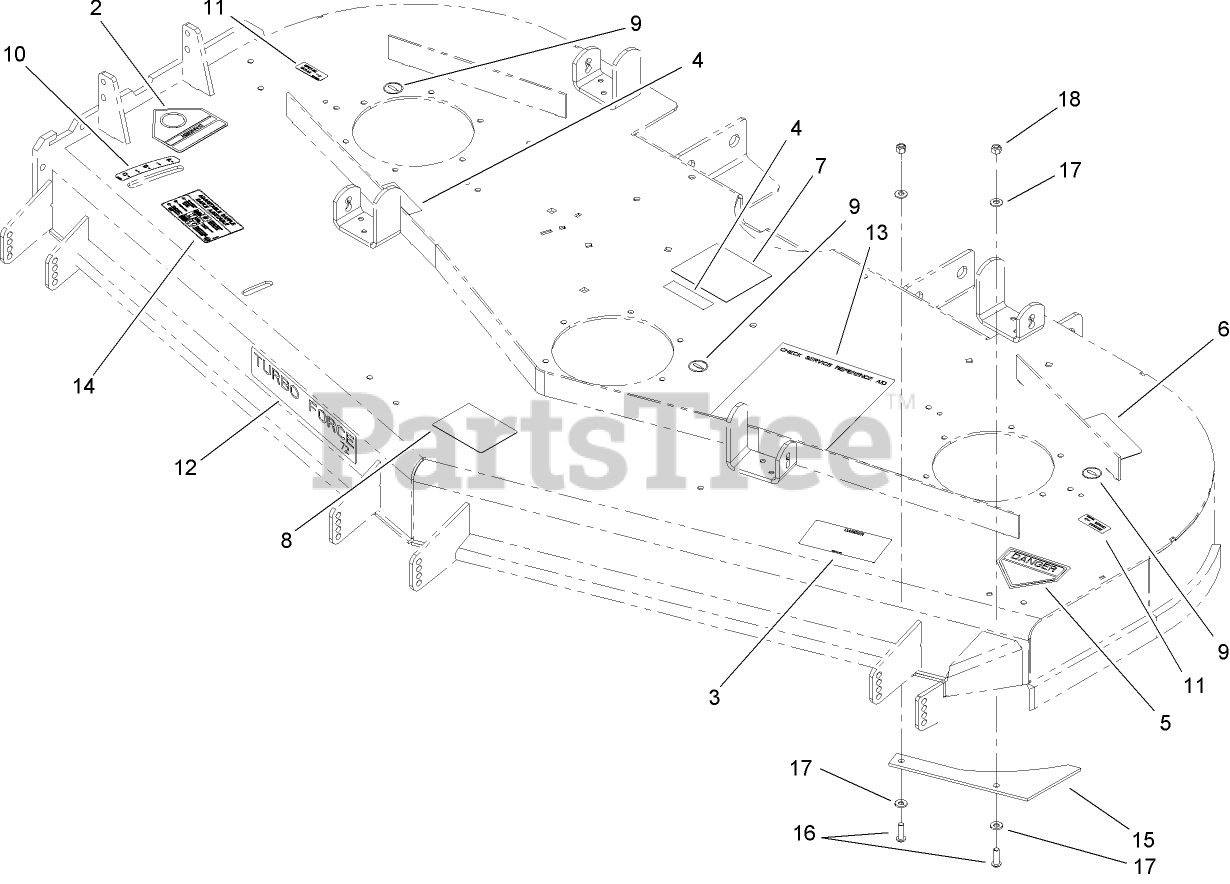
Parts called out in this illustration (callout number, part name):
2	DECAL-DANGER
3	DECAL-DANGER, THROWN OBJECT
4	DECAL-COVER, MISSING
5	DECAL-DANGER
6	DECAL-TORQUE
7	Decal-Routing, Belt
8	DECAL-SCALP, ANTI
9	DECAL-GREASE
10	DECAL-SETTING, BAFFLE
11	Decal-Grease
13	Decal-Service, Check
14	DECAL-ADJUSTMENT, BAFFLE
15	PLATE-TURBO
16	SCREW-HSBH
17	WASHER-SPRING
18	NUT-LOCK, NI
